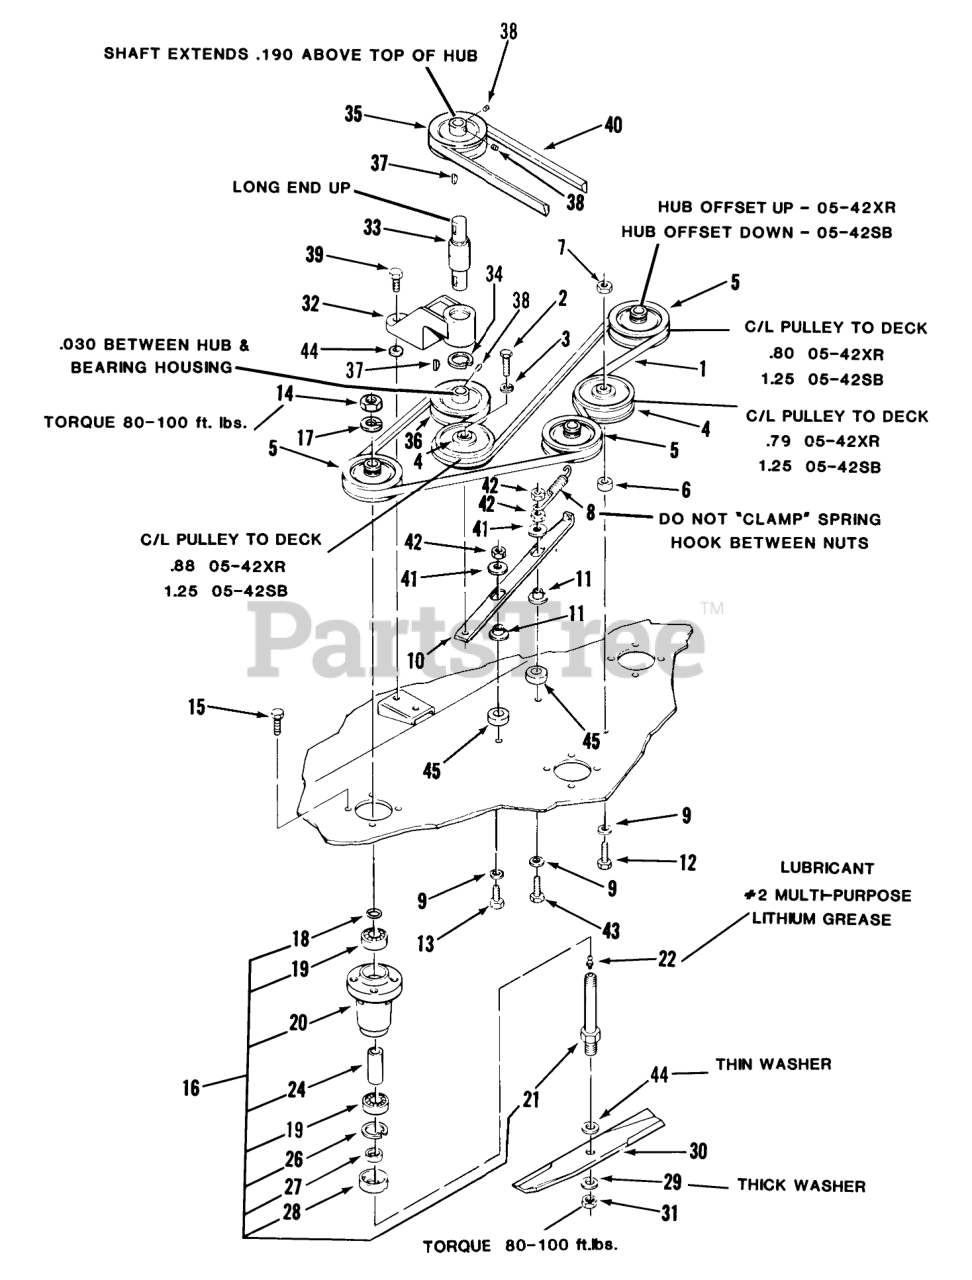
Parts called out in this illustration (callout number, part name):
1	V-BELT
2	Bolt
2	BOLT HEX SPECIAL
3	LOCKWASHER
4	Idler Pulley
5	PULLEY
6	SPACER
7	Nut
8	SPRING-EXTENSION
9	WASHER
10	BAR-SLIDER
11	SPACER-BUSHING
12	Bolt
13	BOLT
13	Bolt
14	Jam Nut
15	Bolt
16	Spindle Assembly
17	Lockwasher
18	O RING
19	BEARING-BALL
20	HOUSING-SPINDLE
21	Spindle Shaft
22	Zerk
26	Ring-Snap
27	SPACER-BLADE
28	CUP-SPINDLE
29	SpeciaI Washer
30	14IN BLADE KIT
30	BLADE KIT
31	Nut-Jam
32	HOUSING DRIVE BRG R
33	BEARING-INT SHAFT
34	Snap Ring
35	PULLEY
36	PULLEY-SPLIT
37	KEY-WOODRUFF
38	Set Screw
39	Bolt
40	V-BELT
41	WASHER
42	Nut
42	NUT
43	Bolt
44	Washer
45	SPACER
